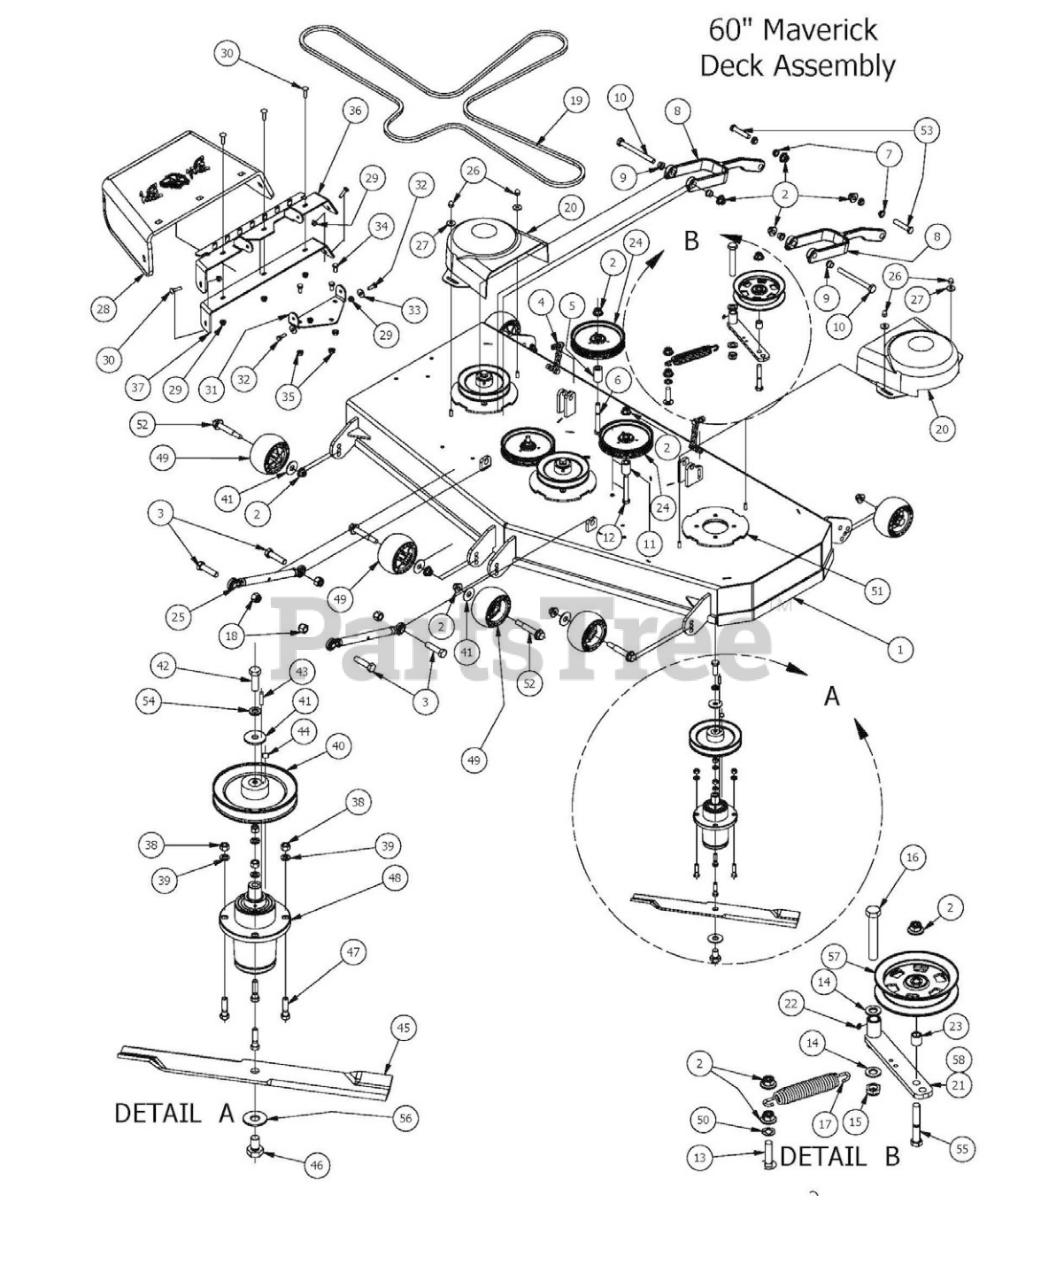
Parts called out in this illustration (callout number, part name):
1	60" ZT/Maverick Deck
2	1/2-13 Nylon Flange Nut
3	5/8" x 2 1/2" Grade 5 Hex Bolt (Coarse)
4	6 Link Chain assembly
5	1 3/4" Pulley Spacer
6	1/2" x 4" Bolt (Grade 8)
7	Flange Bushing For Lower Deck Arm
8	Deck Arm Assembly
9	Flange Bushing For Upper Deck Arm
10	1/2" x 5 1/2" Bolt
11	Idler Pulley Standoff
12	1/2 x 3 1/2 Flange Bolt Grade 8
13	1/2 x 2" Carriage Bolt
14	.630 ID Plastic Washer
15	5/8-11 Nylon Insert Jam Half Nut
16	5/8" x 4" Hex Bolt
17	2015 Deck Idler Spring
18	5/8 Std NC Nylock Nut
19	60" ZT Deck Belt
20	2014 ZT Pulley Cover
21	Deck Idler
22	1/4" Drive in Grease Fitting
23	Spacer 3/4 OD x 1/2 ID x 314 Length
24	5-3/4 Idler Pulley
25	Tumbuckle (Top Link)
26	Acorn nut-pulley Cover
27	.360 ID Plastic Washer-Black
28	Rubber Discharge Chute
29	5/16" Nylon Flange Nut
30	5/16" x 1 1/4" Carriage Bolt
31	Discharge Chute Hanger (Deck Mounted)
32	5/16" x 1" Bolt
33	.360 ID Plastic Washer
34	3/8" x 3/4" Hex Bolt
35	3/8" Flange Nut
36	60" Discharge Chute Upper Hanger
37	60" Lower Hanger
38	3/8" Hex Nut
39	3/8" Lock Washer
40	6 1/4" Drive Pulley
41	1/2" belleville Washer
42	1/2"-20 x 1 1/2 - Grade 5 Fine Thread Bolt
43	1/4" x 1" Key
44	5/16 Set Screw
45	60 Inch Fusion Blade
46	5/8" x 1 1/2" Grade 8 Hex Bolt (Fine)
47	3/8" x 1 1/2" Hex Bolt
48	Spindle Assembly
49	Anti-Scalp Roller
50	.517 Square Hole Round Washer
51	Deck Spindle Support Plate
52	Deck Wheel Bolt
53	1/2" x 3" Hex Bolt
54	1/2" Lock Washer
55	1/2 x 2-3/4 Hex Bolt
56	5/8" Flat Washer
57	5" Idler Pully
58	Deck Idler Assembly (Components 2,21,22,23,55,57)
